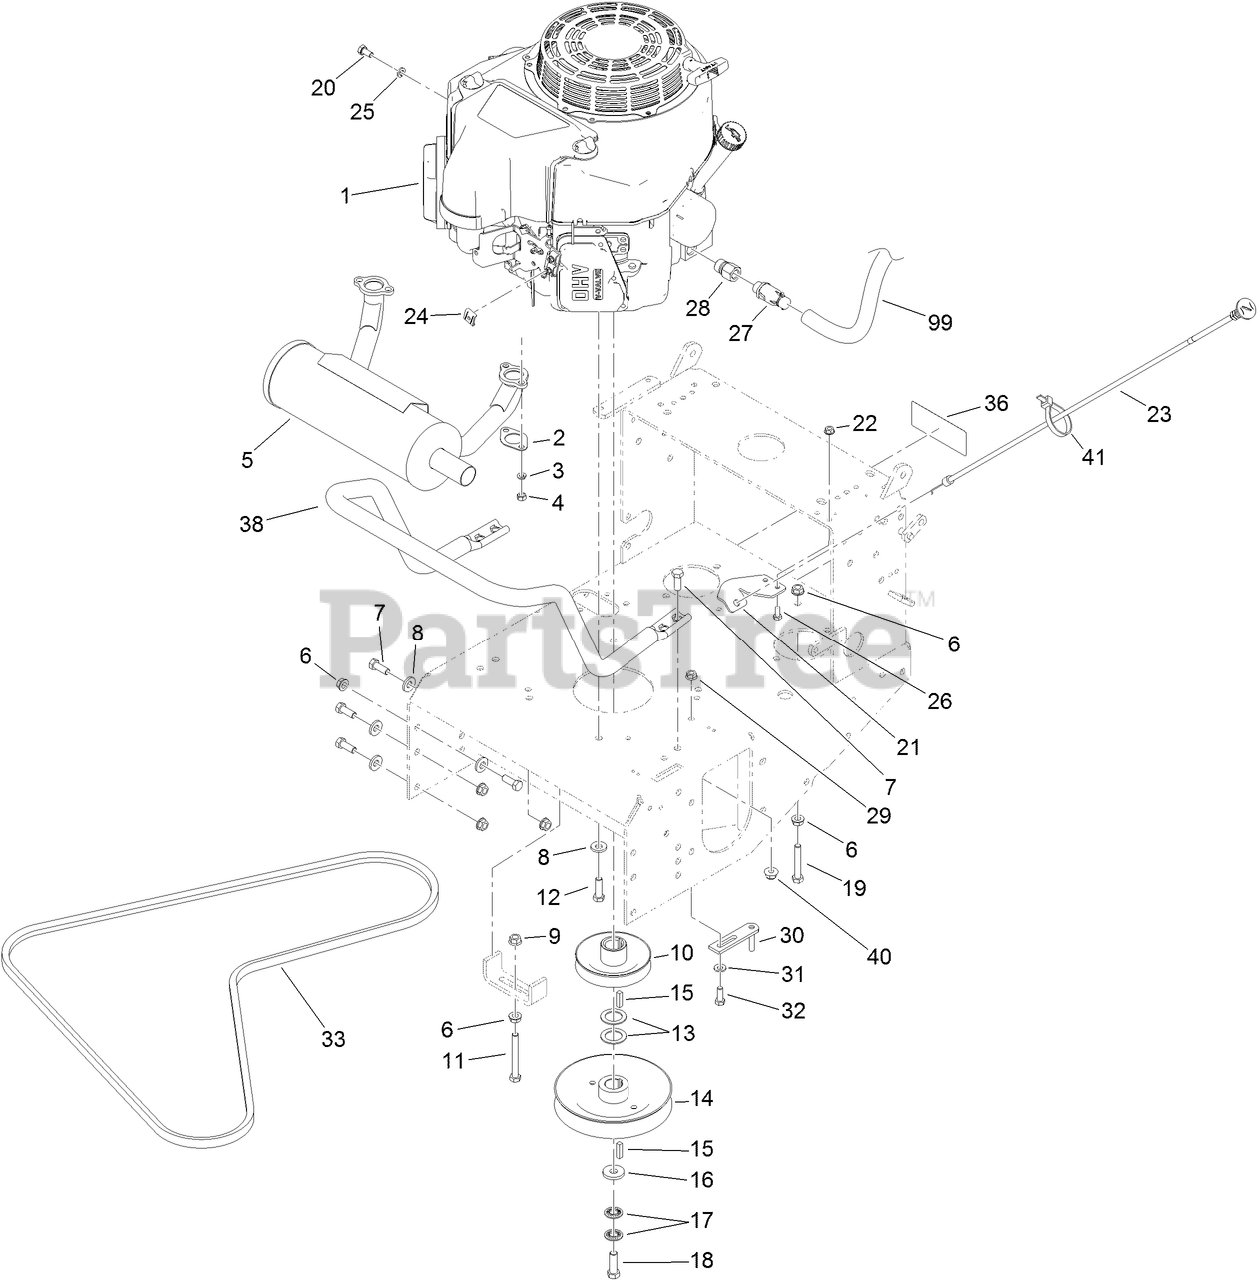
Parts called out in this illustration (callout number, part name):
2	GASKET-EXHAUST
3	WASHER-LOCK
5	MUFFLER-HORIZONTAL, OFFSET
6	NUT-HHF, WHIZ
7	SCREW-HH
8	WASHER-BELLEVILLE
9	NUT-HF
10	PULLEY
11	SCREW-HH
12	SCREW-HH
13	WASHER-SPACER
14	PULLEY
16	WASHER
17	WASHER-SPRING
18	SCREW-HH
19	SCREW-HH
20	SCREW-HH
21	Bracket-Cable, Choke
22	NUT-HF
23	Cable-Choke
24	CLAMP-CABLE
25	WASHER-LOCK
26	SCREW-HH
27	VALVE-DRAIN, OIL
28	Adapter
29	NUT-HF
30	GUIDE-BELT
31	WASHER-SPRING
32	SCREW-HH
33	BELT-V
36	DECAL-WARNING, SULKY
38	GUARD-MUFFLER
40	NUT-HF, NI
41	TIE-CABLE
99	HOSE-DRAIN, OIL
